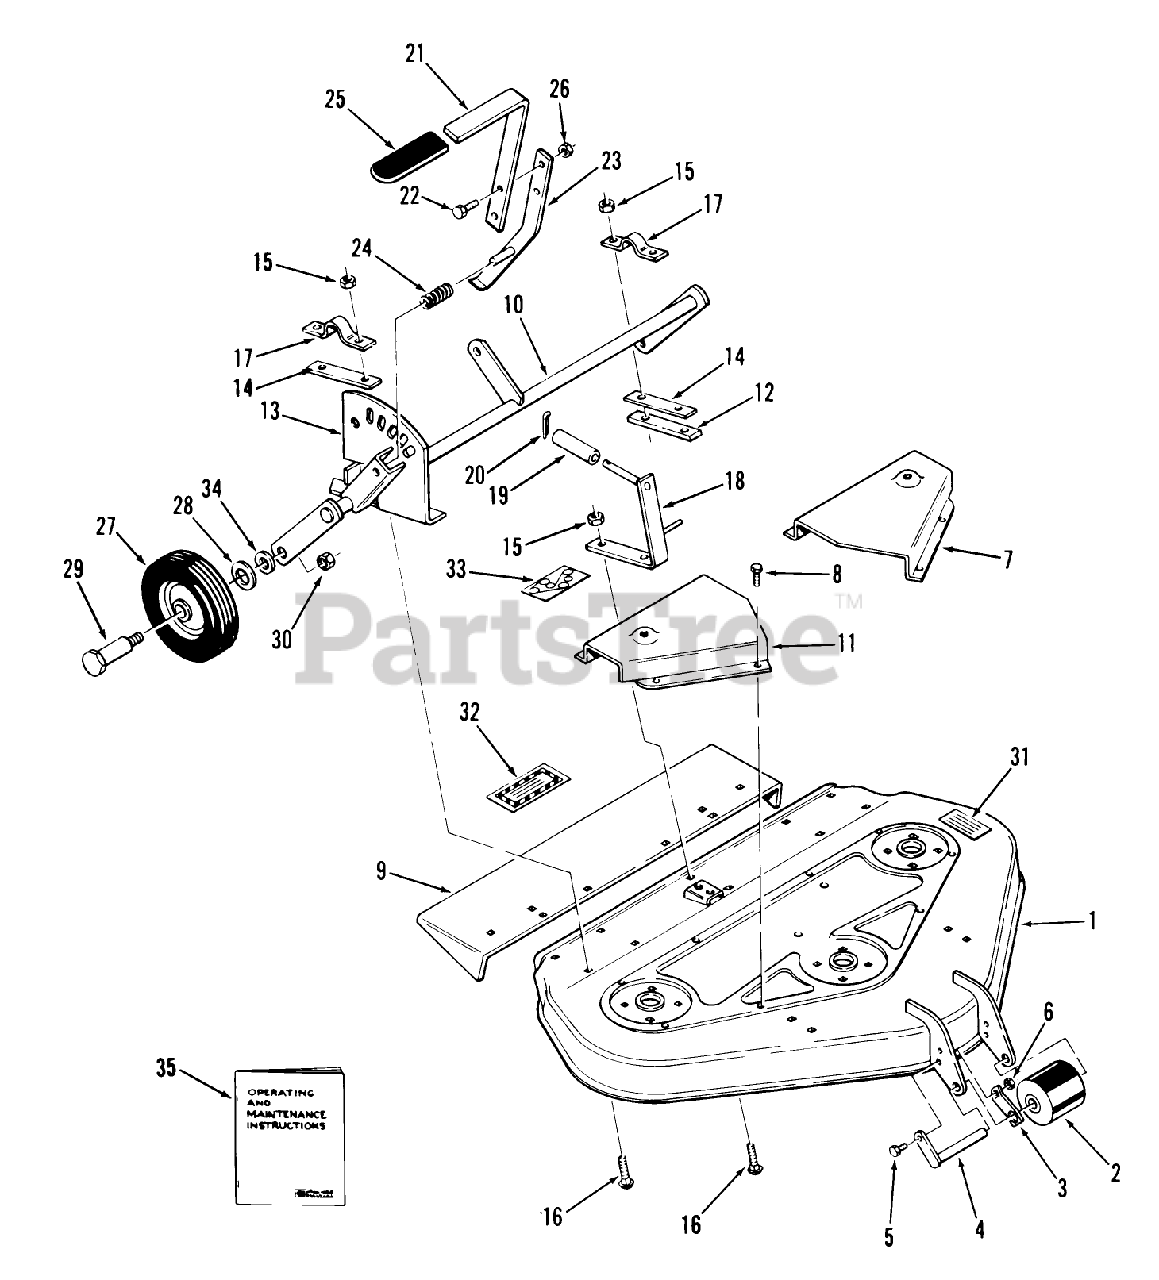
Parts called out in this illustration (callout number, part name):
1	ASSY-MOWER DECK RH
8	Bolt
21	HANDLE-EXTENSION *R
24	SPRING-COMPRESSION
28	WASHER-FLAT
29	BOLT-SHOULDER
33	DECAL-HEIGHT BELT
35	Operating and Maintenance Instructions
